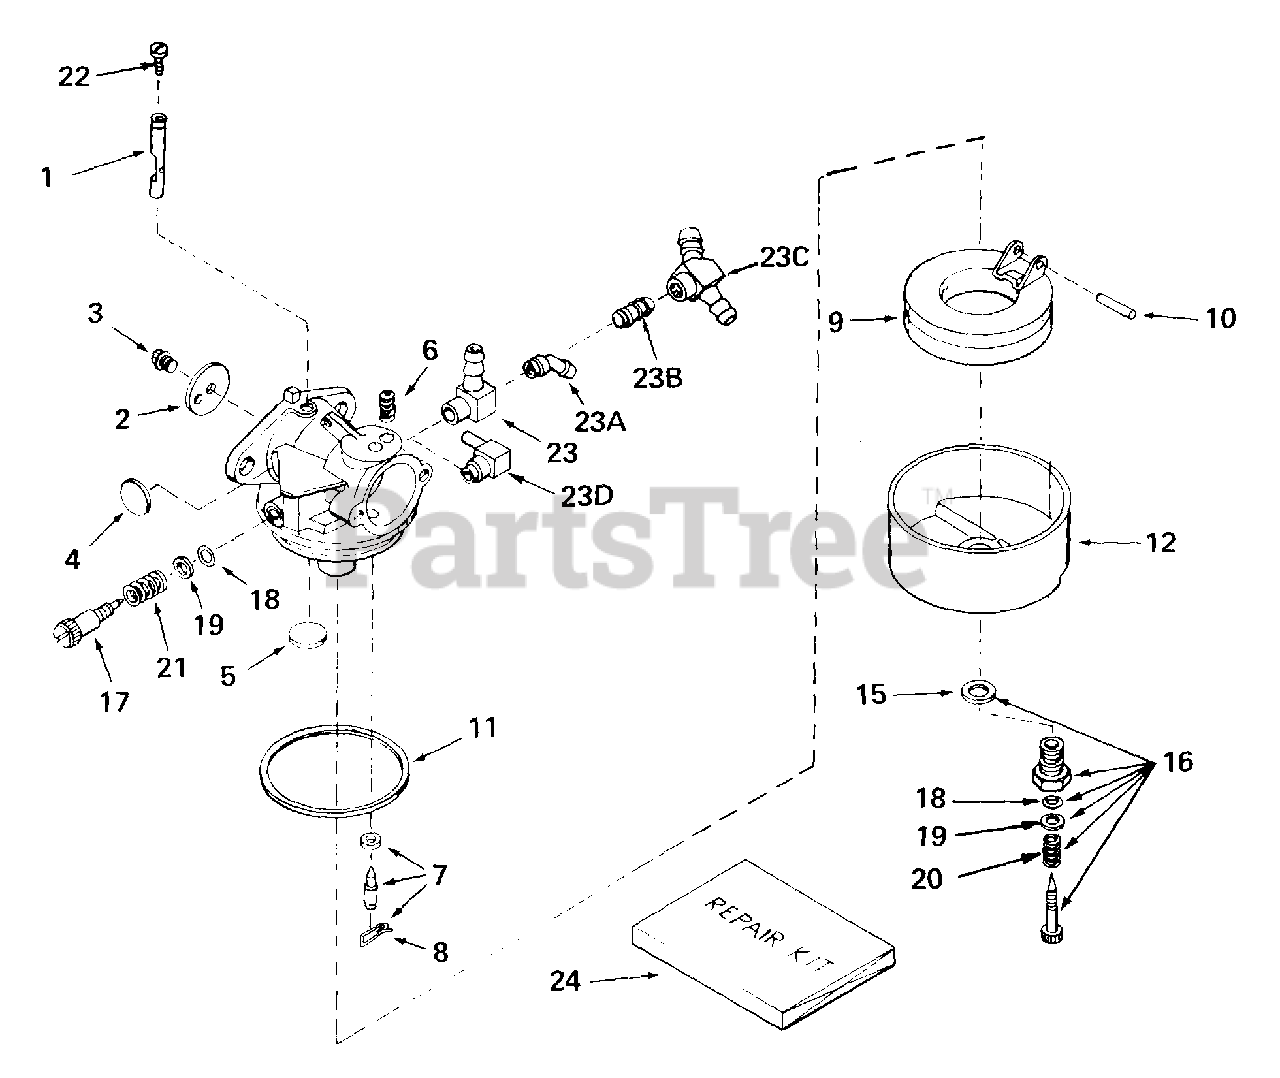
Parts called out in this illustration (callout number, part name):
1	"Shaft,Throttle
2	Shutter, Throttle
3	Screw, 4-40 x 3/16
4	Plug, Welch
5	Plug, Welch
6	Spring, Choke positioning
7	Inlet Needle, Seat & Clip
8	Clip, Inlet needle
9	Float, Carburetor
10	Shaft, Float.
11	Gasket, Bowl-to-body
12	Bowl, Float
15	Gasket, Bowl-to-Body
16	Adjustment Screw Assy., Main
17	Screw, Idle adjustment
18	"O" Ring, Adjustment screw
20	Spring, Adjustment screw
21	Spring, Adjustment screw
22	Screw, Pan hd taptite, 4-40 x 1/4
23	Fitting, Fuel inlet
23A	Fitting, Fuel inlet
24	Repair Kit
